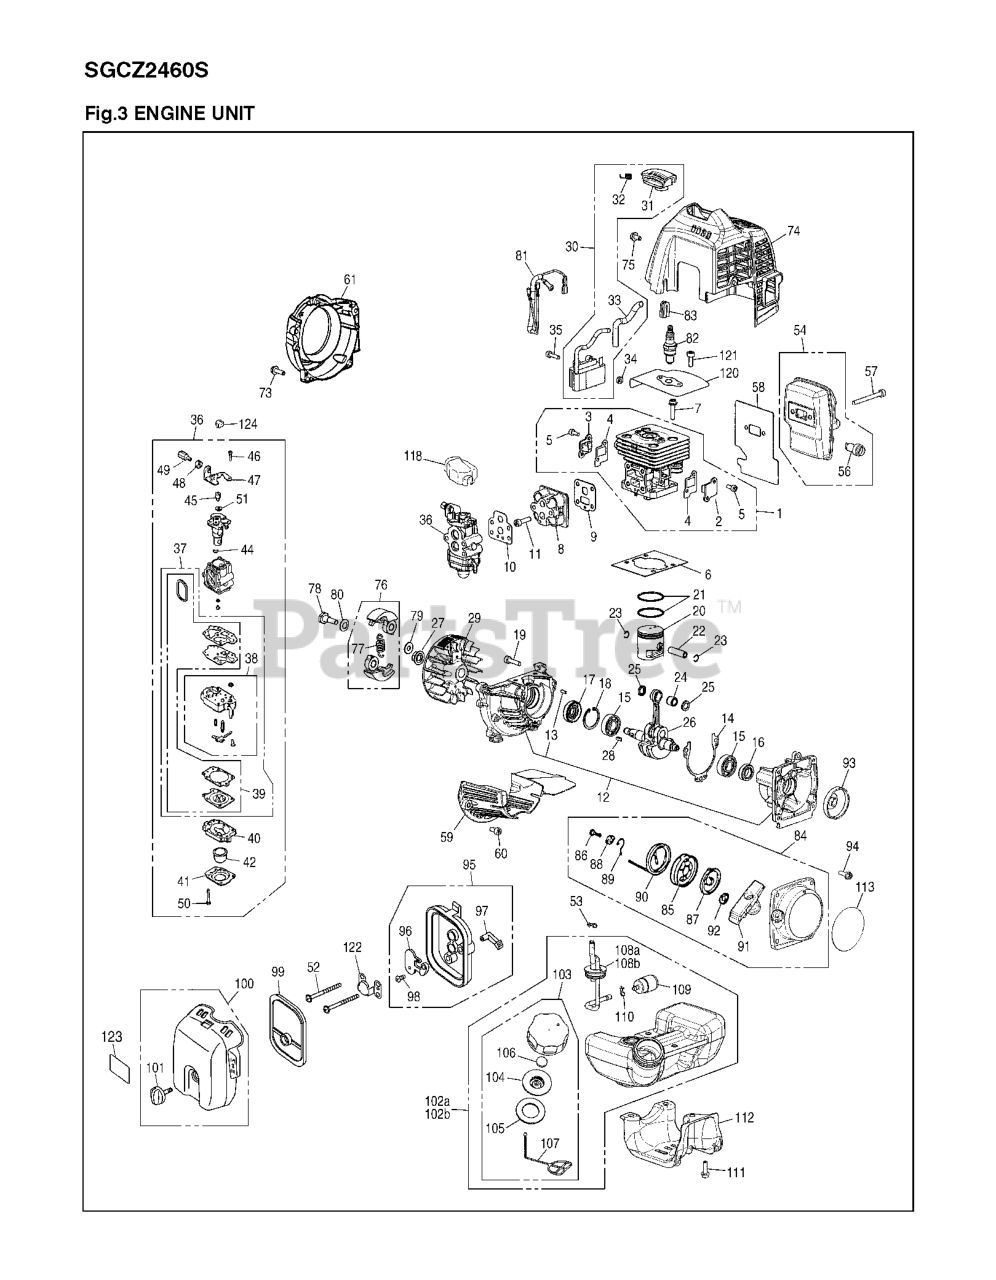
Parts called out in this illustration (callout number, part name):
1	CYLINDER COMP
2	COVER, TR-S
3	COVER, TR-F
4	GASKET, TR
5	BOLT
6	GASKET, BASE
7	BOLT
8	INSULATOR
9	INSULATOR GASKET(R-848F0814B0)
10	GASKET, CARB
11	BOLT TORX
12	CRANKCASE-C
13	PIN
14	GASKET, CASE
17	SEAL
22	PIN
26	CRANKSHAFT-C
27	NUT
28	KEY
30	COIL ASSY
34	SPACER
36	CARBURETOR ASSY
37	REBUILD KIT
38	CARBURETOR BODY
39	GASKET KIT
41	1OVER
44	RING
45	SWIVEL
46	SCREW
47	BRACKET
49	ADJUSTER
51	WASHER
52	BOLT TORX
53	CLIP
56	ARRESTER
58	GASKET, MUFFLER
74	COVER, ENGINE
75	BOLT (RPLS T495051010-11)
76	SHOE COMP
81	CORD-COMP
82	SPARK PLUG CMR7H-10
84	RECOIL ASSY
87	SPRING, SPIRAL
88	COLLAR
89	SWING ARM
92	PLATE.STOPPER
94	CLIP
95	CLEANER BODY ASSY
96	PLATE, CHOKE
98	SCREW
99	ELEMENT
100	COVER ASSY
101	Cleaner Knob
102	TANK ASSY
104	HOLDER-A
108	PIPE-C
108	PIPE ASSY
109	FILTER
110	CLIP
113	LABEL, RECOIL
